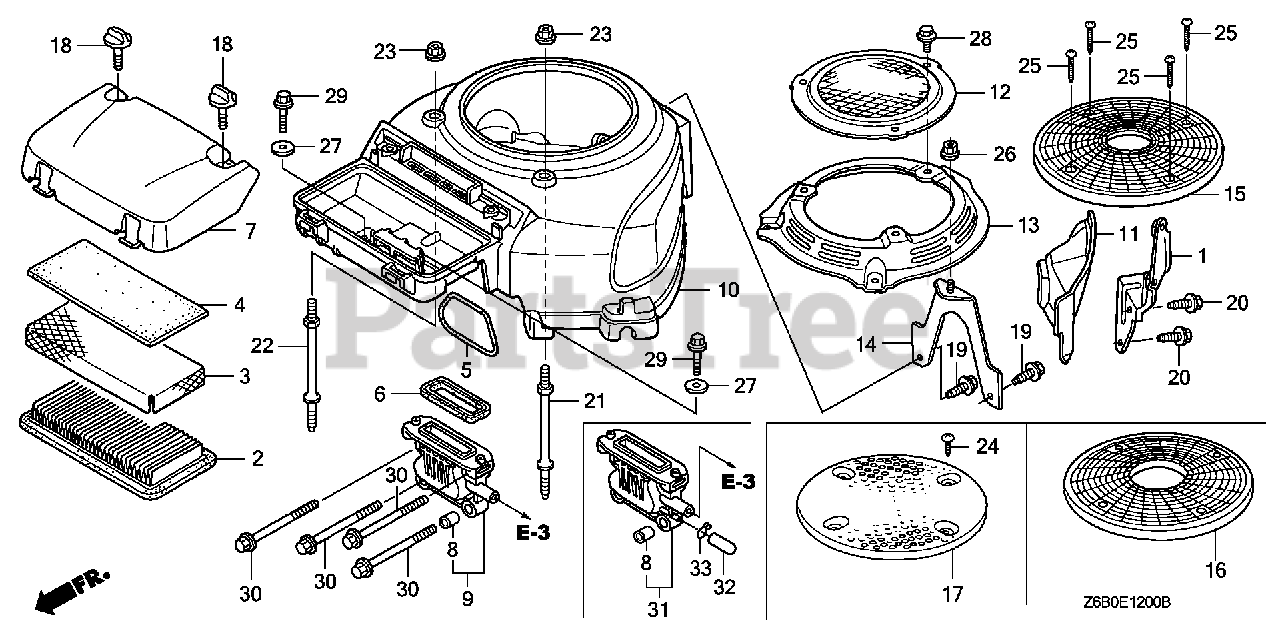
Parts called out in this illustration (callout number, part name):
2	ELEMENT, AIR CLEANER
3	GRID, AIR CLEANER
4	FILTER (OUTER)
5	GASKET, AIR CLEANER
6	SEAL, AIR CLEANER HOUSING
7	COVER, AIR CLEANER
8	COLLAR A, AIR CLEANER
9	ELBOW, AIR CLEANER
10	COVER, FAN *NH1* (BLACK)
10	COVER, FAN *R280* (POWER RED)
11	PLATE, SIDE
12	PROTECTOR, FAN COVER *NH105* (MAT BLACK)
12	PROTECTOR, FAN COVER *R280* (POWER RED)
13	SPACER, RECOIL STARTER MOUNTING *NH105* (MAT BLACK)
13	SPACER, RECOIL STARTER MOUNTING *R280* (POWER RED)
14	BRACKET, RECOIL MOUNT
15	GRID, SCREEN (D50) *NH1* (BLACK)
15	GRID, SCREEN (D50) *R280* (POWER RED)
18	BOLT, AIR CLEANER (6MM)
19	BOLT, FLANGE (6X14) (CT200)
20	BOLT, FLANGE (6X14)
21	BOLT, L. STUD (IGNITION COIL)
22	BOLT, R. STUD (IGNITION COIL)
23	NUT, FLANGE (6MM)
25	SCREW, TAPPING (4X30) (PO)
26	NUT, FLANGE (6MM)
27	WASHER, PLAIN (6MM)
28	BOLT, FLANGE (6X8)
29	BOLT, FLANGE (6X12) Use up to Engine SN 1543277.
30	BOLT, FLANGE (6X100)
